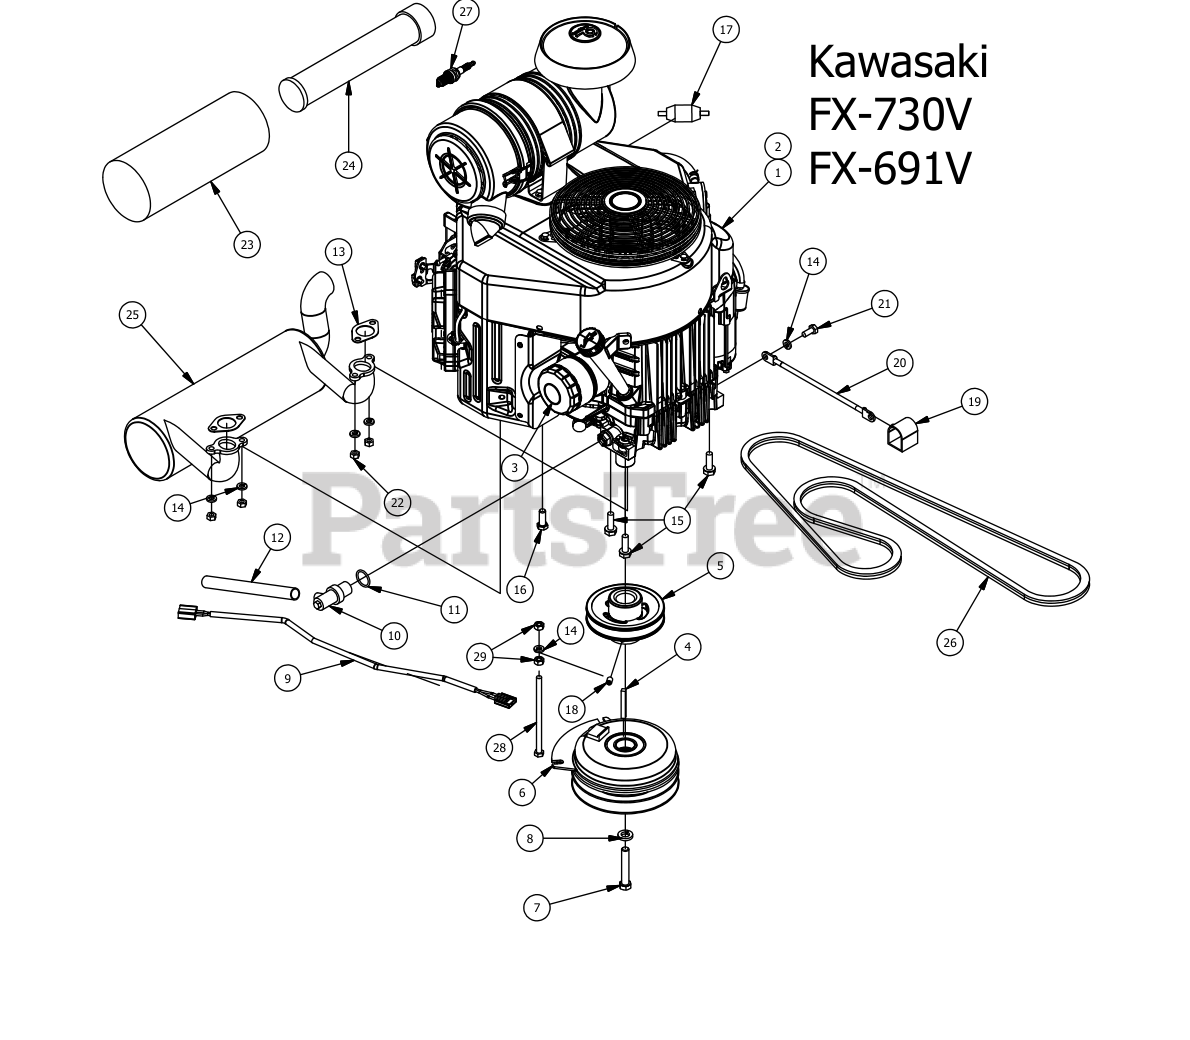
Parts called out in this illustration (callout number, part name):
3	Kawasaki Oil Filter
4	1/4 x 2 Square key Stock
5	4 3/4 Motor Pulley
6	Clutch Assembly
7	7/16" x 2 1/2" Hex Bolt
8	7/16" Lock Washer
9	Clutch Pigtail
12	1/2 Clear Braded Hose Priced/Foot
13	Exhaust Gasket
14	5/16" Lock Washer
15	3/8 x 1 1/8 bolt
16	3/8" x 1" Hex Bolt
17	Universal Inline Fuel Filter
18	5/16 Set Screw
19	Black Boot For Ground Cable
20	Ground Cable
21	M8x1.20x20MM Hex head bolt
22	M8-1.25 Zinc Nut
23	Canister Air Filter- Outer
24	Canister Air Filter- Inner
25	Exhaust- 2015 Stand On
27	Spark Plug - Kawasaki
28	5/16-18 x 5-1/2 GR 5 Hex Bolt
